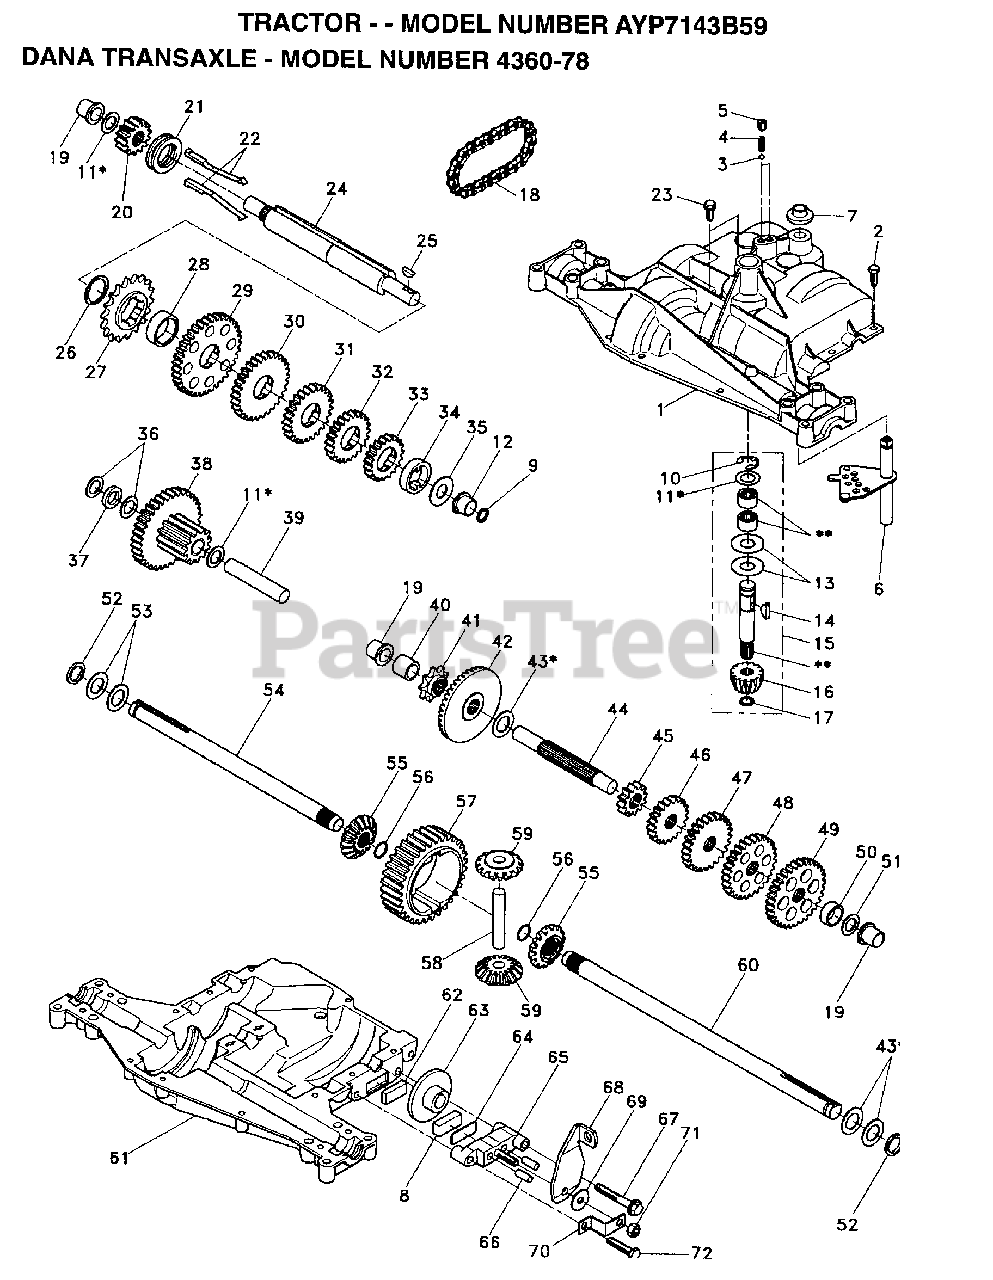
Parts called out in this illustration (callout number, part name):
1	HOUSING, UPPER
3	BALL, DETENT
4	SPRING, DETENT
5	SCREW, SET
6	SHIFTER ASSEMBLY
7	BOOT, SHIFTER
8	PUCK, FRICTION
10	RING, RETAINING
11	ASSY, KIT, SHIM .625 SHAFT
12	BEARING, FLANGE
13	WASHER, PLAIN .632 X 1.38 X .046
14	KEY, WOODRUFF, #9
15	ASSEMBLY, KIT, INPUT SHAFT
16	PINION, BEVEL, 14 TEETH
17	RING, RETAINING
18	CHAIN, 24 PITCHES
19	BEARING, FLANGE
20	GEAR, SPUR, 14 TEETH
21	COLLAR, CLUTCH
21	GEAR, SPUR, 25 TEETH
22	ASSEMBLY, KIT, CLUTCH KEYS
23	SCREW TAPPING WITH SEALER
24	SHAFT, INTERMEDIATE
25	KEY, WOODRUFF, #61
26	RING, RETAINING
27	SPROCKET, 18 TEETH
29	GEAR, SPUR, 37 TEETH
30	GEAR, SPUR, 30 TEETH
32	GEAR, SPUR, 22 TEETH
33	GEAR, SPUR, 19 TEETH
35	WASHER, PLAIN .640 X 1.37 X .061
36	WASHER, PLAIN .632 X 1.00 X .026
37	SPACER .630 X 1.00 X .169
38	ASSY GEAR COMB 12&35 TEETH
39	SHAFT, IDLER
40	SPACER .635 X .875 X .755
41	SPROCKET, 9 TEETH
42	GEAR, BEVEL, 42 TEETH
43	ASSY, KIT, SHIM .750 SHAFT
44	SHAFT, DRIVE
45	GEAR SPUR, 12 TEETH
46	GEAR, SPUR, 20 TEETH
47	GEAR, SPUR, 25 TEETH
48	GEAR, SPUR, 28 TEETH
49	GEAR, SPUR, 31 TEETH
51	WASHER, PLAIN .632 X 1.00 X .060
52	WASHER, NEOPRENE
53	WASHER, PLAIN .758 X 1.25 X .031
54	AXLE LEFT HAND
55	GEAR, MITER, 15 TEETH
56	RING, RETAINING
57	GEAR, SPUR, 32 TEETH
58	SHAFT, CROSS
59	GEAR, SPUR 30T
60	AXLE, R.H.
61	HOUSING, LOWER
62	PUCK, FRICTION
63	DISC, BRAKE
65	JAW, BRAKE
66	PIN, DOWEL
67	SCREW, SELF-TAPPING
68	LEVER ACTUATING
69	WASHER, PLAIN .321 X 1.00 X .055
70	BRACKET, ANTI-ROTATION
71	LOCKNUT 5/16-24
72	SCREW TAPPING
